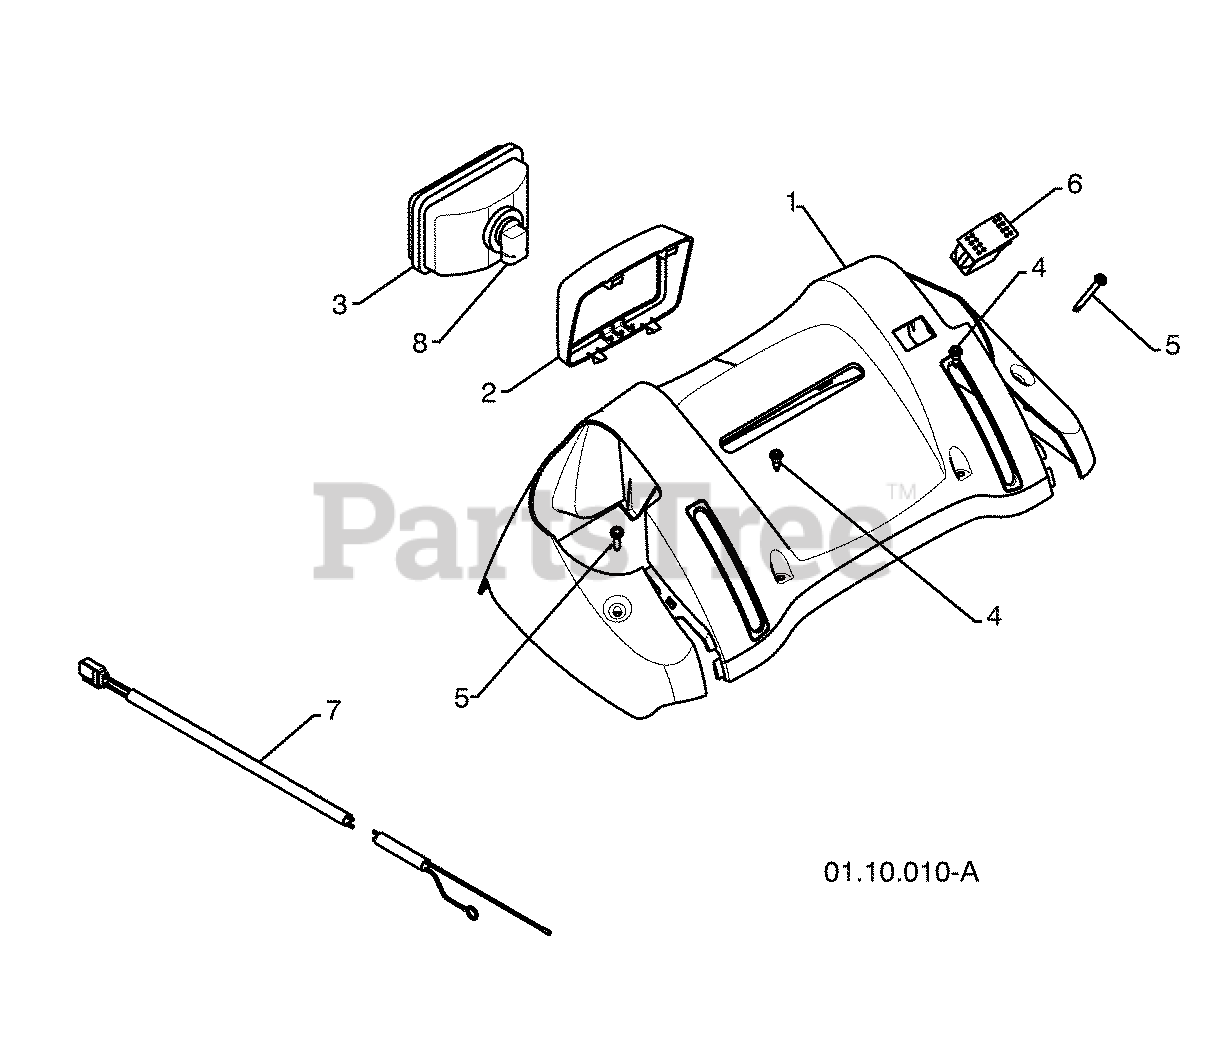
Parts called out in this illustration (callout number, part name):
1	CONSOLE PANEL GRAY
2	HEADLIGHT BEZEL GRAY
3	HALOGEN HEADLIGHT
4	SHOULDER SCREW 10-24 X .625
5	SCREW 10-24 X 1.25
6	GRIP SWITCH
7	WIRE HARNESS
